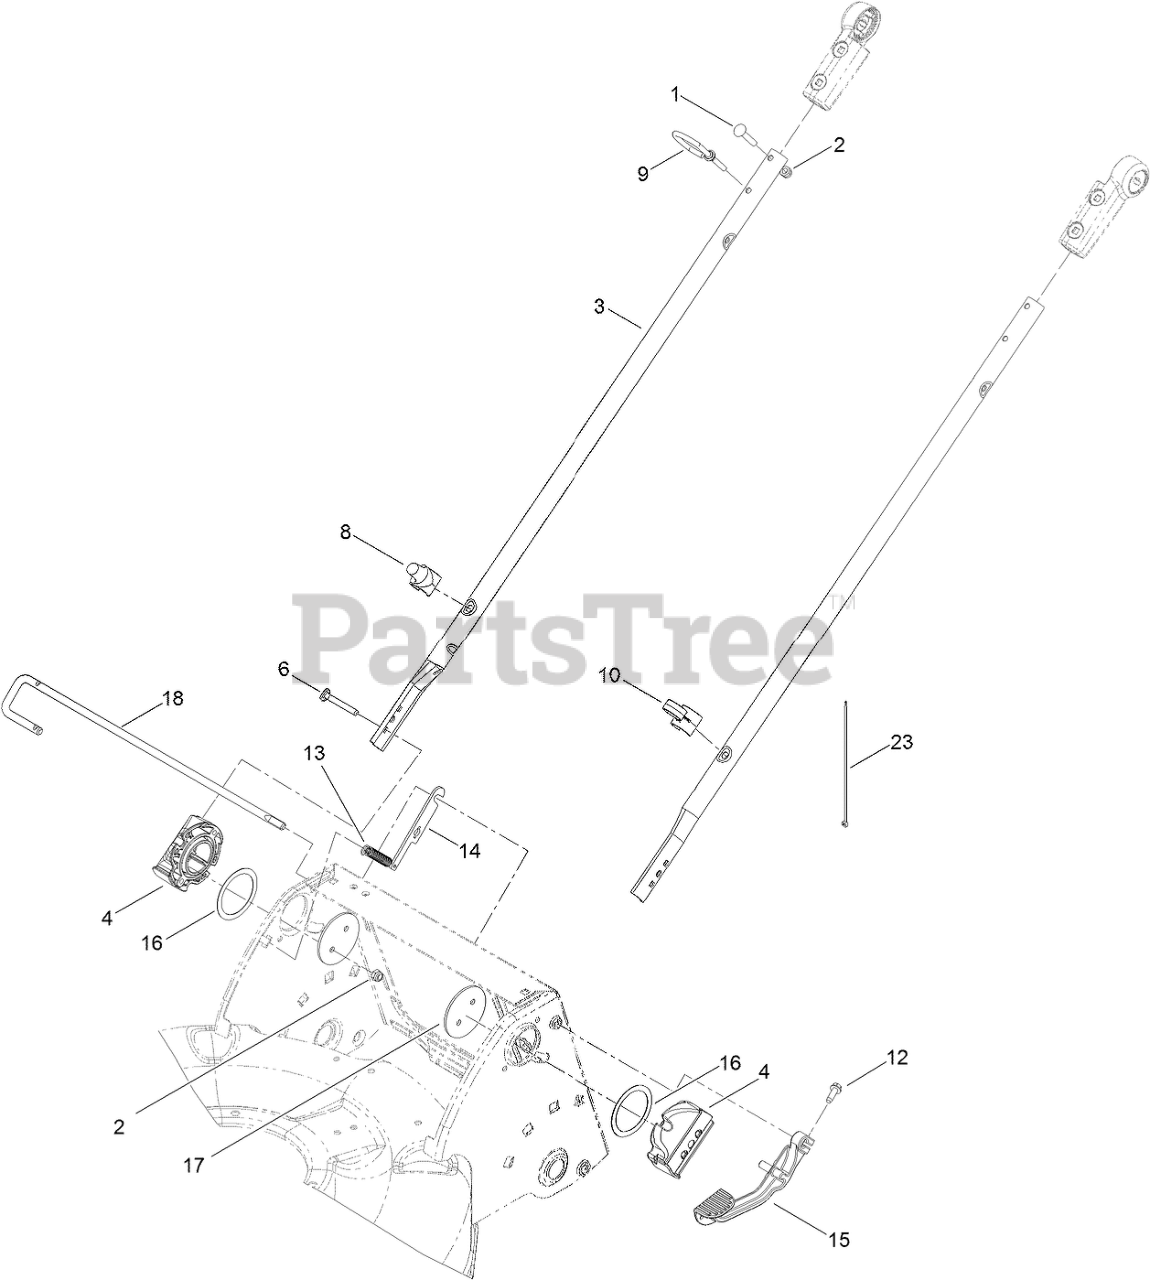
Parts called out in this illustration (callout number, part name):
1	SCREW-CARR
2	NUT-LOCK, NI
3	TUBE-LOWER
4	MOUNT-HANDLE
6	SCREW
8	GUIDE-ROPE, LOWER
9	GUIDE-ROPE, UPPER
10	GUIDE-CABLE
12	SCREW-HWHTF
13	SPRING-EXTENSION
14	PLATE-ROD, RELEASE
15	LEVER-RELEASE
16	WASHER-NYLON
18	ROD-RELEASE, HANDLE
23	TIE-CABLE
